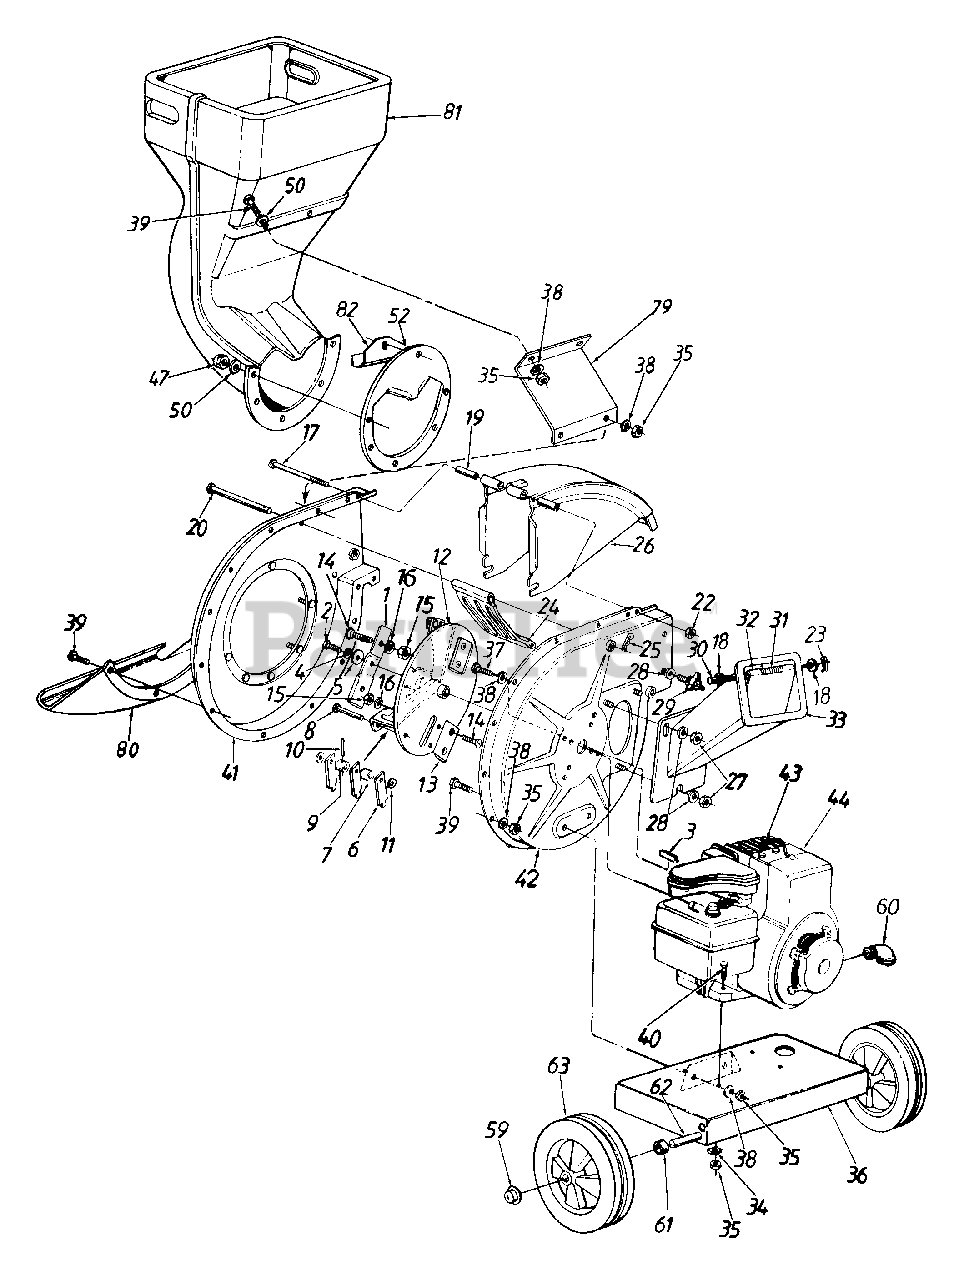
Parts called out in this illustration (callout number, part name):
1	Blade
2	Hex Patch Bolt 3/8-24 x 2" Lg. (Gr. 8)
3	Sq. Key 1/4 x 2.0" Lg.
4	L-Wash. 3/8" I.D. H.D.
5	Fl-Wash. .406" I.D. x 1.25" O.D. Hdn.
6	Flail
7	Flail Spacer
8	Clevis Pin .496" Dia.
9	Flail Spacer w/.160" Dia. Hole
10	Spring Roll Pin 1.12" Lg.
11	Fl-Wash. .531" I.D. x .94" O.D.
12	Impeller Ass'y. Comp.
13	Chipper Blade
14	Flat Hd. Scr. 5/16-24 x .75" Lg.
15	Hex Top L-Nut 5/16-24 (Gr. 5)
16	L-Wash. 5/16" I.D.
17	Hex Bolt 1/4-20 x 3.75" Lg.
18	Fl-Wash. .281" I.D. x .50" O.D.
19	Chute Hinge Spacer 1.66" Lg.
20	Clevis Pin .5" Dia. x 4.62" Lg.
22	Hex Ctr. L-Nut 1/4-20 Thd.
25	Internal Cotter Pin 3/8" Dia.
27	Hex Nut 5/16-18 Thd. (Gr. 5)
28	Bell-Wash. .345" I.D. x .88"
30	Chipper Door Rod
31	Torsion Spring 1.14" Lg.
35	Hex Nut 5/16-18 Thd. (Sr. 5)
37	Hex Bolt 5/16-24 x .75" Lg.
38	L-Wash. 5/16" I.D.
39	Hex Bolt 5/16-18 x .75" Lg. (Gr. 5)
40	Hex Bolt 5/16-18 x 1.5" Lg.
44	Engine
47	Elastic Lock Nut 5/16-18 Thd.
50	Fl-Wash. 5/16" I.D.
52	Back-Up Plate
59	Push Cap 5/8" Dia. Rod
60	Drain Elbow
61	Spacer .64" I.D. x .38" Lg
62	Shredder Axle
63	Wheel Ass'y. Comp.
